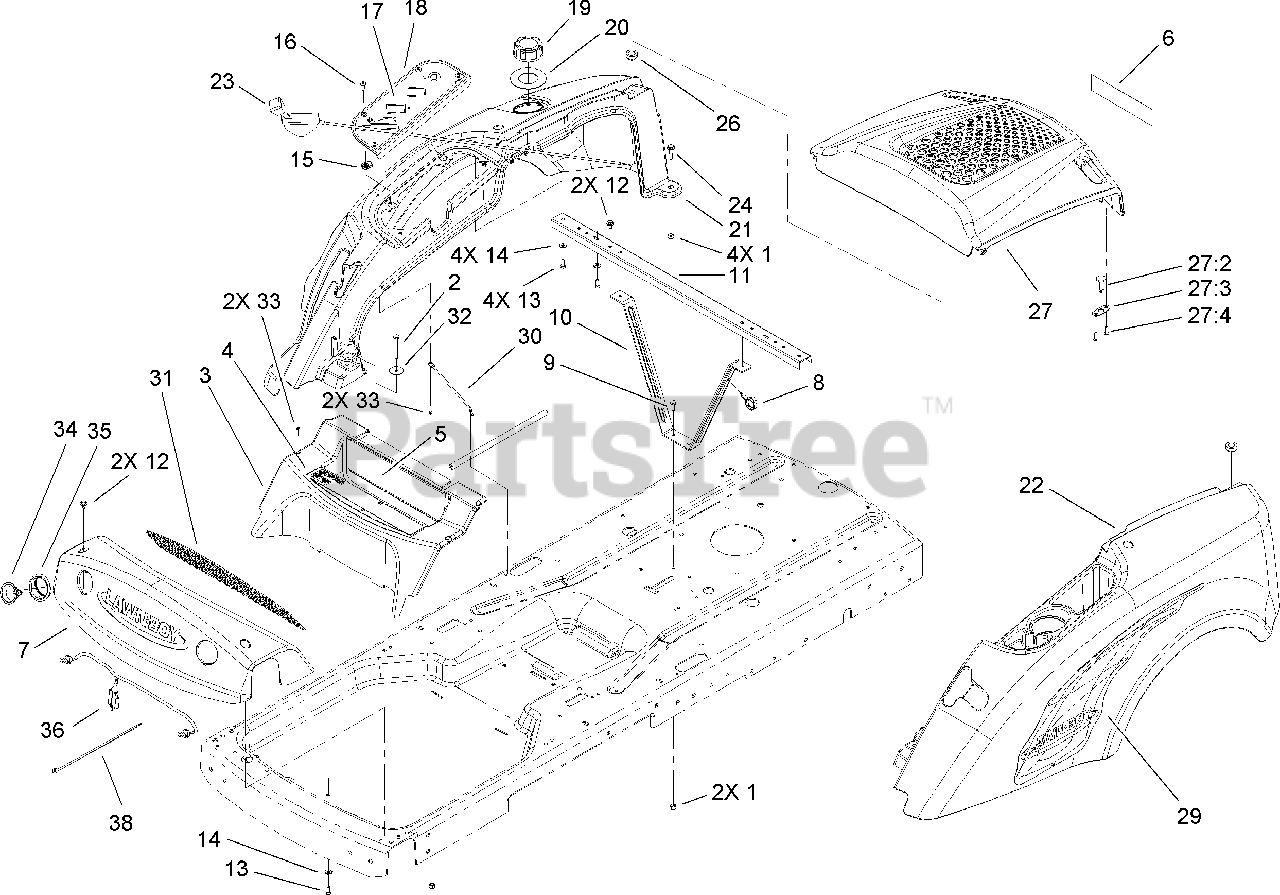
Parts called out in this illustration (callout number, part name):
1	NUT-LOCK, NI
2	SCREW-HH
3	PANEL-KICK
4	DECAL-DANGER, CE
6	DECAL-LOGO
8	CLAMP-HOSE
9	SCREW-HH
10	BRACE-SUPPORT
11	CHANNEL-CROSS
12	SCREW-HHF
13	SCREW-PLASTITE
14	WASHER-FLAT
16	SCREW-PRH
18	PANEL-CONTROL
19	GAS CAP ASM
20	WASHER-SEAL, RUBBER
21	COVER-SIDE, RH
22	COVER-SIDE, LH
23	CABLE-THROTTLE
24	SCREW-SHOULDER
27	HOOD COVER ASM
29	DECAL-SIDE COVER, LH
30	ROD-SUPPORT
31	FOOTMAT-FOOTREST
32	WASHER-FLAT
33	SCREW-PPH
34	LIGHT-HALOGEN
35	BEZEL-RUBBER
36	HARNESS-HEADLIGHTS, FOOTREST
38	TIE-CABLE
